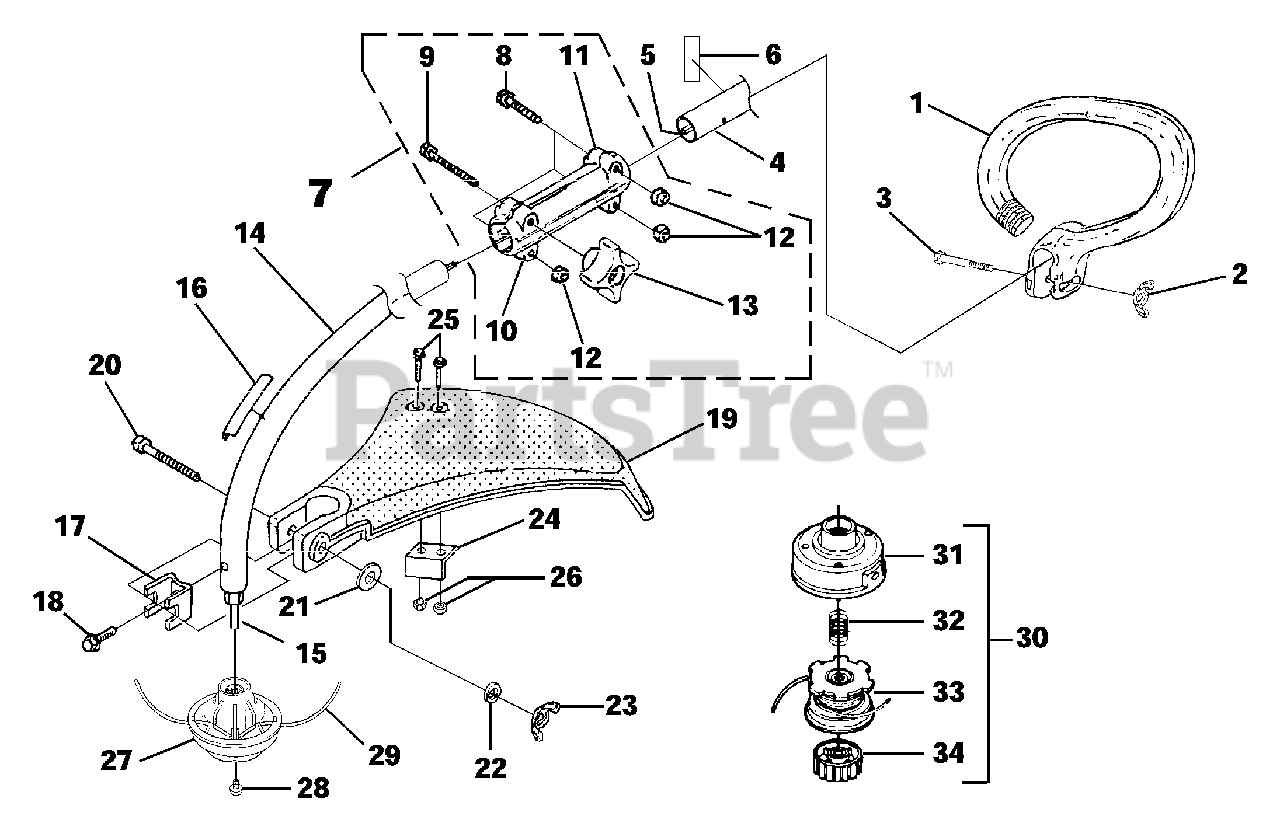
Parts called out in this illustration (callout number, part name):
1	HANDLE-Anti-Vibe
2	NUT-Wing, Washer Faced (1/4-20)
3	SCREW-Cap Hex Hd. (1/4-20 x 2")
4	DRIVESHAFT ASSY. (Upper)
5	FLEXSHAFT w/Collar & Liner
6	DECAL-Warning
7	COUPLER ASSEMBLY
8	SCREW-Hex Hd. (1/4-20 x 1 1/2")
9	SCREW-Cap Hex (1/4-20 x 2")
10	COUPLER (L.H.)
11	COUPLER (R.H.)
12	NUT-Hex (1/4-20)
13	KNOB (1/4-20)
14	DRIVESHAFT HOUSING (Lower)
15	SHAFT-Flex
16	DECAL-Warning
17	CLAMP
18	SCREW-Sems Hex (10-24 X 3/8")
19	DEFLECTOR & BLADE KIT (55 Deg.)
20	SCREW-Cap Hex Hd. (10-24 X 2")
21	WASHER-Flat (1/4")
22	WASHER-Lock (1/4")
23	NUT-Wing, Washer Faced (1/4-20)
24	BLADE-Cut-Off
25	SCREW-Mech. Hex Hd. (10-24 X 7/8")
26	NUT-Hex (10-24)
27	STRINGHEAD-Pro-Cut w/line (UT20710)
28	SCREW-(5/16-18 x 5/8")
29	LINE-Replacement
30	STRINGHEAD-Complete (.080") (UT20712)
31	HOUSING & EYELET (Dual Line)
32	SPRING-Compression
33	SPOOL & STRING (.080")
34	RETAINER-Spool (R.H. Thread, Black)
